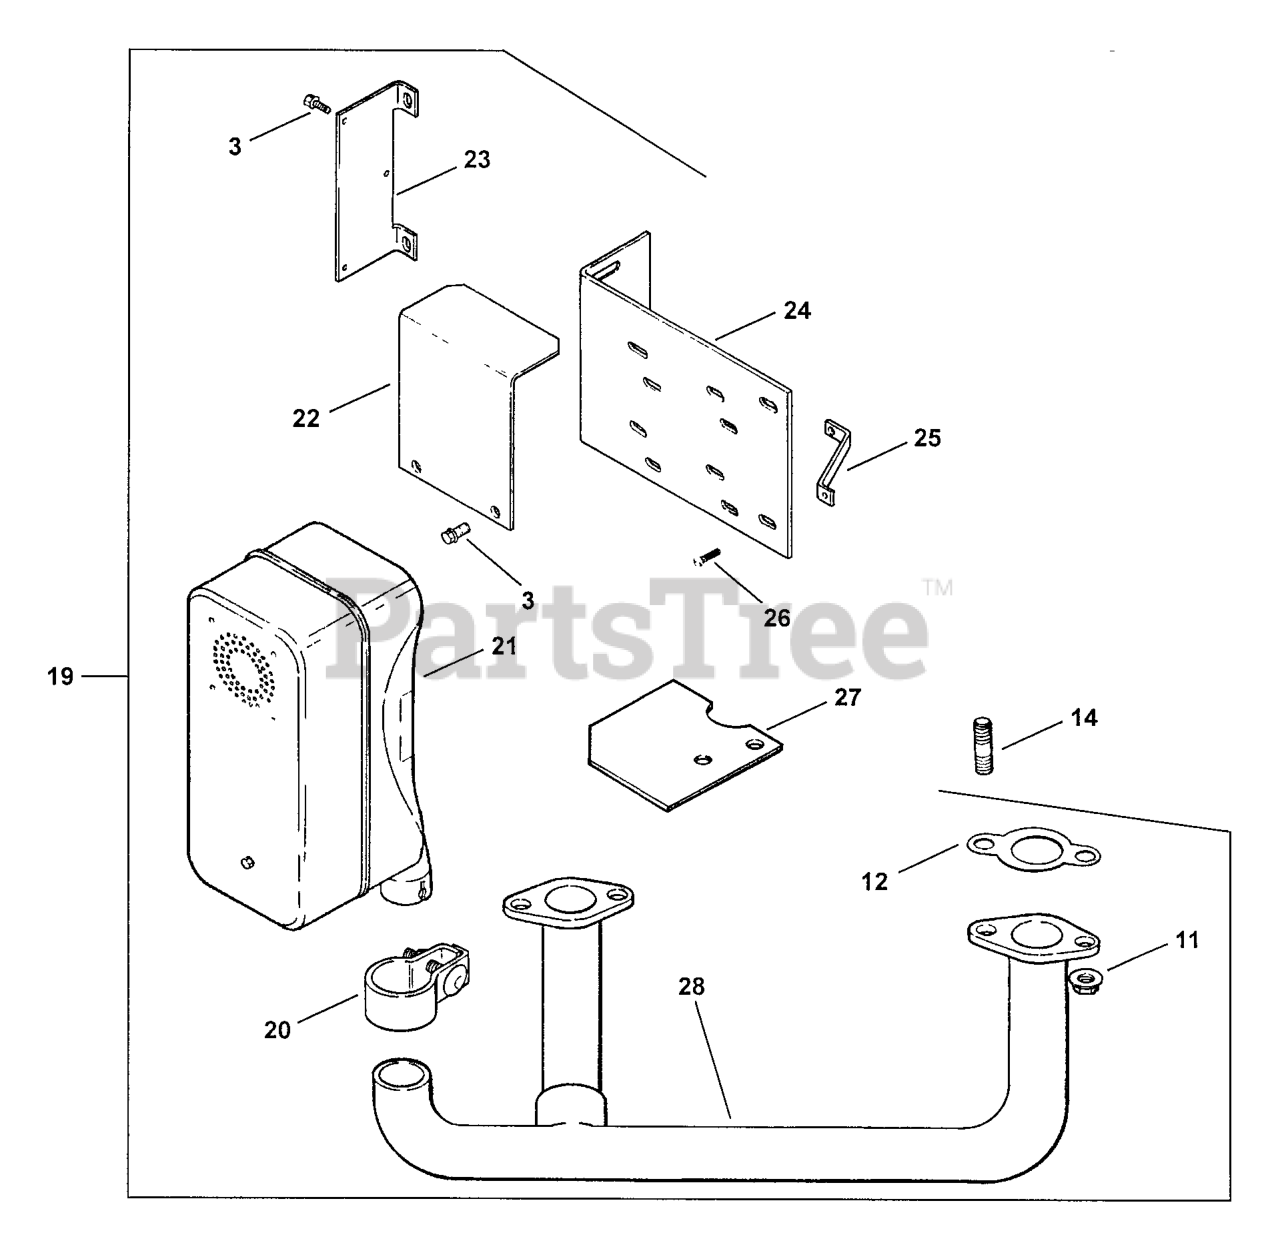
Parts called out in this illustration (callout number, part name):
11	Nut, Hex. Flange M8x1.25
12	Gasket, Exhaust
14	Stud, Exhaust M8x1.25x20
